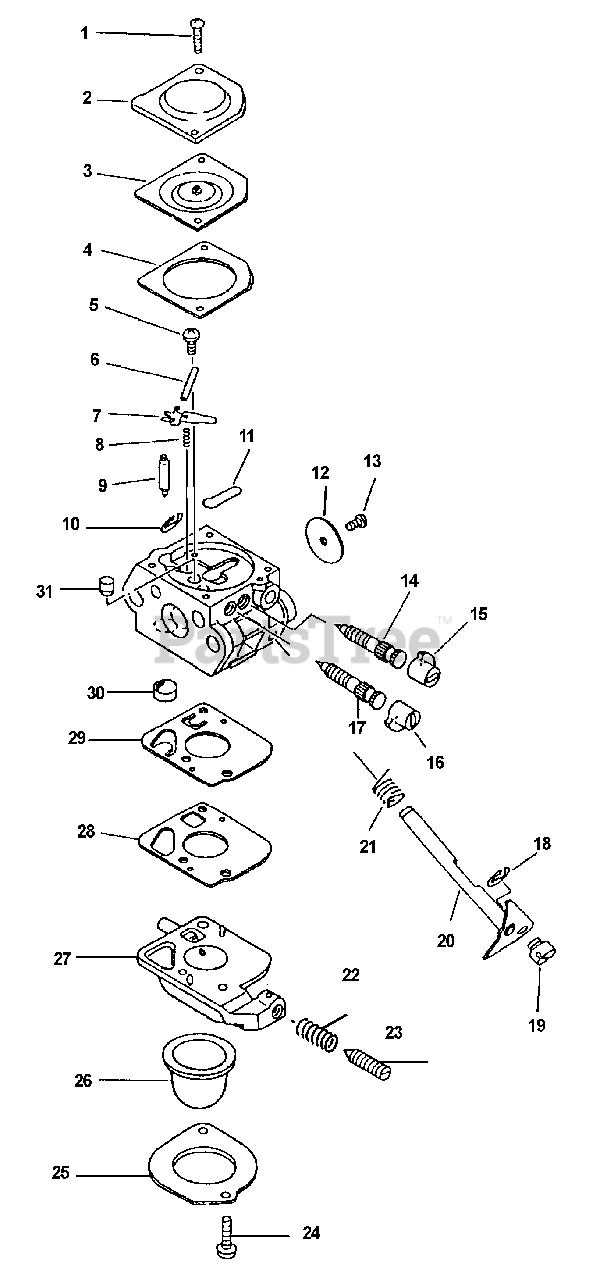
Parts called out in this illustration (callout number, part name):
2	Cover, metering diaphragm
3	Diaphragm, metering
4	Gasket, metering diaphragm
6	Pin, metering lever
7	Lever, metering
8	Spring, lever metering
9	Needle, inlet
11	Plug, welch
12	Valve, throttle
14	Needle, lo speed
15	Cap, lo speed limiter
16	Cap, hi speed limiter
17	Needle, hi speed
20	Shaft, throttle
21	Spring, throttle return
22	Piece, friction
23	Screw, idle adjust
25	Retainer, purge pump
26	Pump, purge
27	Base, purge
28	Gasket, fuel pump
29	Diaphragm, fuel pump
30	Strainer
31	Nozzle, check valve
